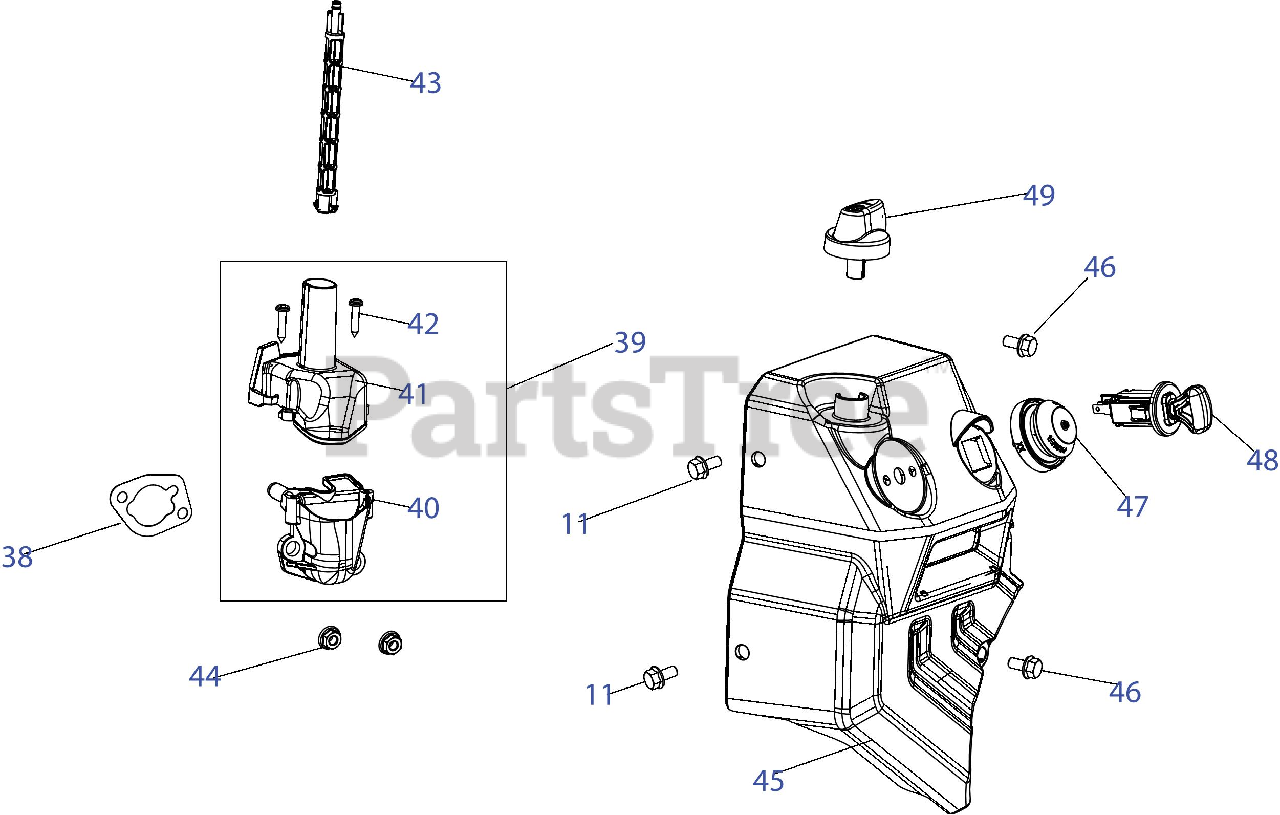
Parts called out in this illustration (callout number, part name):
11	Bolt, M6x12
38	Gasket, Air Filter
39	Heater Box
40	Air Filter Base
41	Upper Cover, Heater Box
42	Self-tappling Screw, ST4.2x16
43	Choke Linkage
45	Control Panel
46	Bolt, M6x18
48	Stop Switch
48	Stop Switch Key
49	Choke Lever
